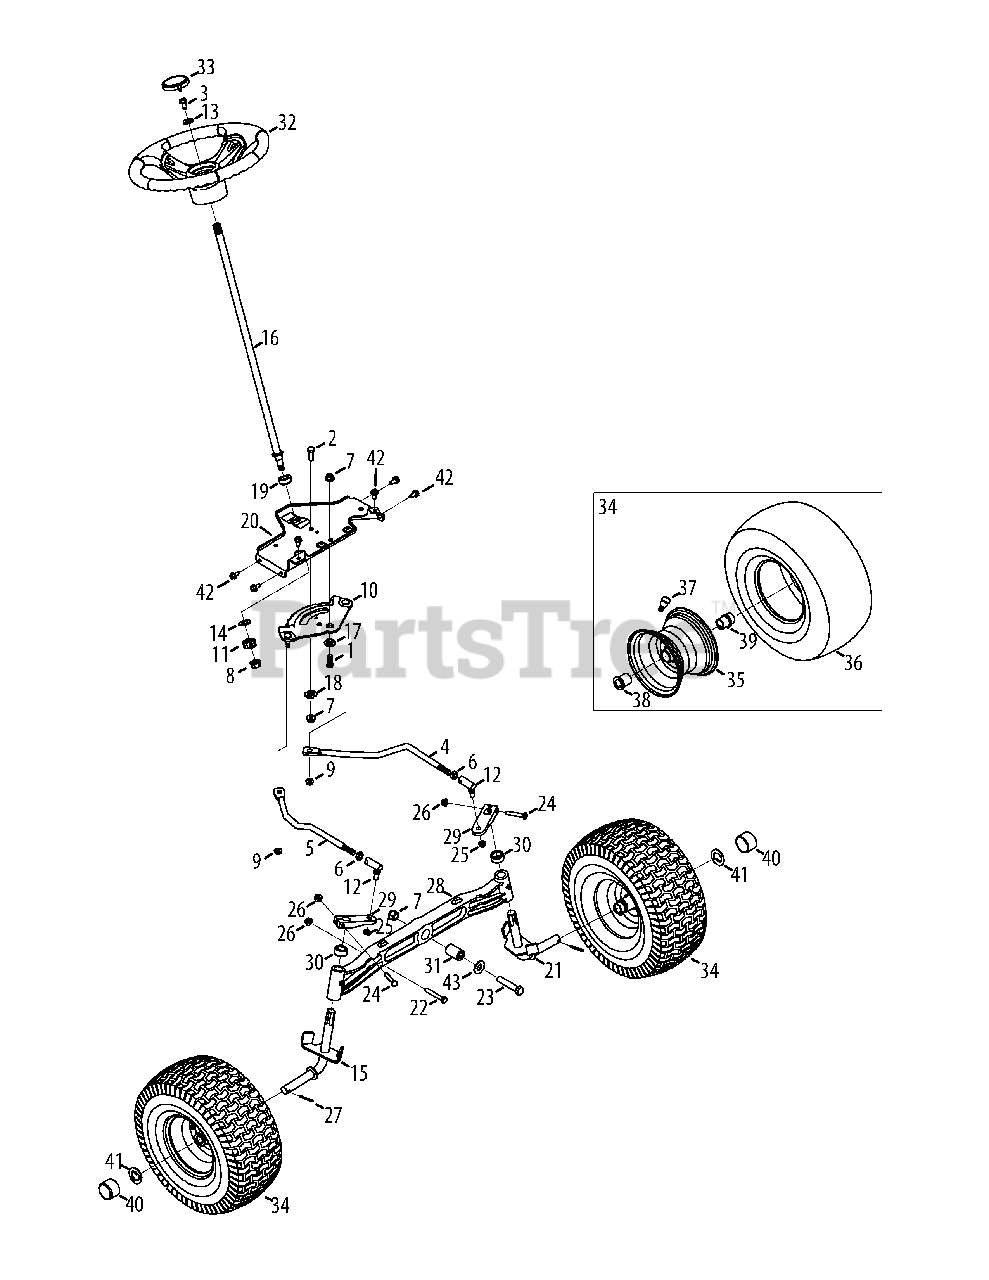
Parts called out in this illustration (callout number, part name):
1	Hex Head Screw, 3/8-16 x 1.00
2	Hex Head Screw, 3/8-16 x 1.00
3	Hex Head Screw, 5/16-18 x 1.00
4	LH Drag Link
5	RH Drag Link
6	Jam Nut, 7/16-20
7	Flangelock Nut, 3/8-16
8	Flangelock Nut, 7/16-20
9	Flangelock Nut, 5/16-18
10	Steering Gear
11	Steering Pinion Gear
12	Ball Joint, 7/16-20
13	Flat Washer, .406 x .875 x .105
14	Flat Washer, .51 x 1.12 x .06
15	RH Axle Assembly
16	Steering Shaft, .625 OD x 24.25 LG
17	Shoulder Spacer, .385 x 1.25 x .3025
18	Spacer, .38 x 1.375
19	Hex Flange Bearing 5/8 PM
20	Steering Support Bracket
21	LH Axle Assembly
22	Hex Head Screw, 5/16-18 x 2.25
23	Hex Head Screw, 3/8-16 x 2.50
24	Hex Head Screw, 5/16-18 x 1.75
25	Hexlock Nut, 3/8-24
26	Flangelock Nut, 5/16-18
27	Cotter Pin, 5/32 x 1.25
28	Pivot Bar Axle
29	Steering, Block
30	Spacer, .71 ID x .125 OD x .56LG
31	Spacer, .385 x 1.00 x 1.5075
32	Steering Wheel, Soft Grip
33	Cap, Troy-Bilt
34	Wheel Assembly
35	Rim Assembly
37	Tubeless Air Valve
38	Flange Bearing, .760 x 1.00 x 1.20LG
39	Flange Bearing, .760ID
40	Bumper Cap
41	Flat Washer, .781ID x 1.590OD
42	Screw, Self-tapping, 5/16-18, .750,
43	Washer, Flat, .406 x .875 x .059
